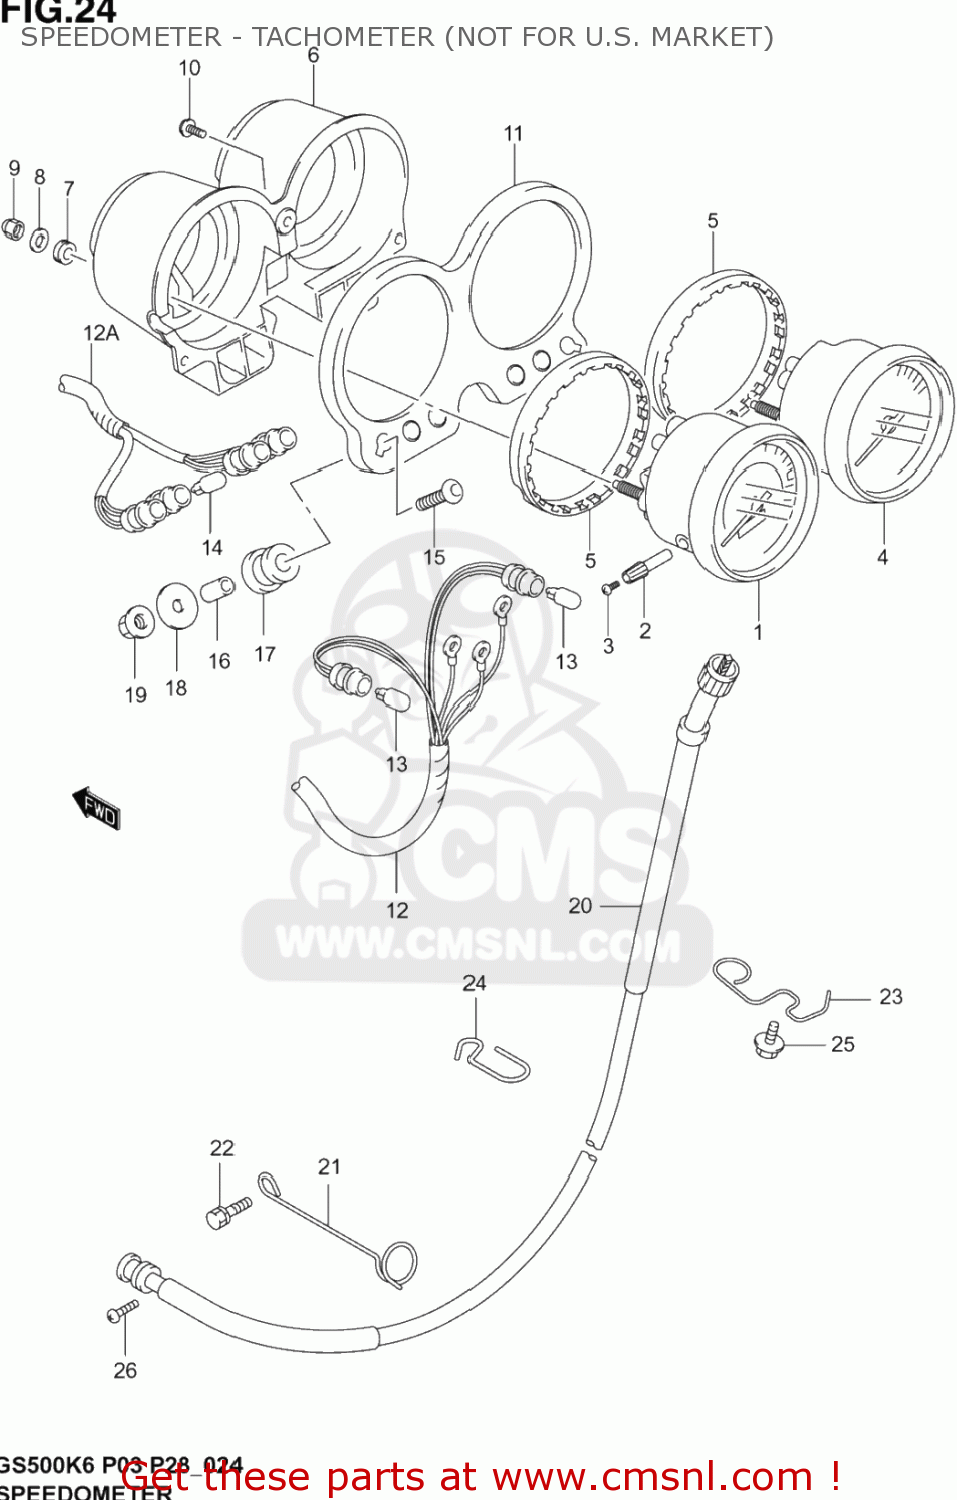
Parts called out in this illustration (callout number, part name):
1	SPEEDOMETER
2	KNOB
3	SCREW(2X6)
4	TACHOMETER
5	DAMPER
6	COVER
7	CUSHION
8	WASHER(5.2X16X1)
9	NUT
10	SCREW
11	BRACKET METER
12	SOCKET&CORD
12A	SOCKETS&CORD
13	BULB(12V1.7W,T10,WB121)
14	BULB(12V1.7W,T10)
15	BOLT(6X30)
16	SPACER(6.5X10X16.5)
17	CUSHION,METER BRACKET
18	WASHER(6.5X28X1.6)
19	NUT
20	CABLE ASSY,SPEEDOMETER
21	CLAMP,SPEEDOMETER CABLE
22	BOLT OIL LEVEL
23	GUIDE,SPEEDOMETER CABLE NO.2
24	GUIDE,SPEEDOMETER CABLE NO.3
25	BOLT OIL LEVEL
26	SCREW
